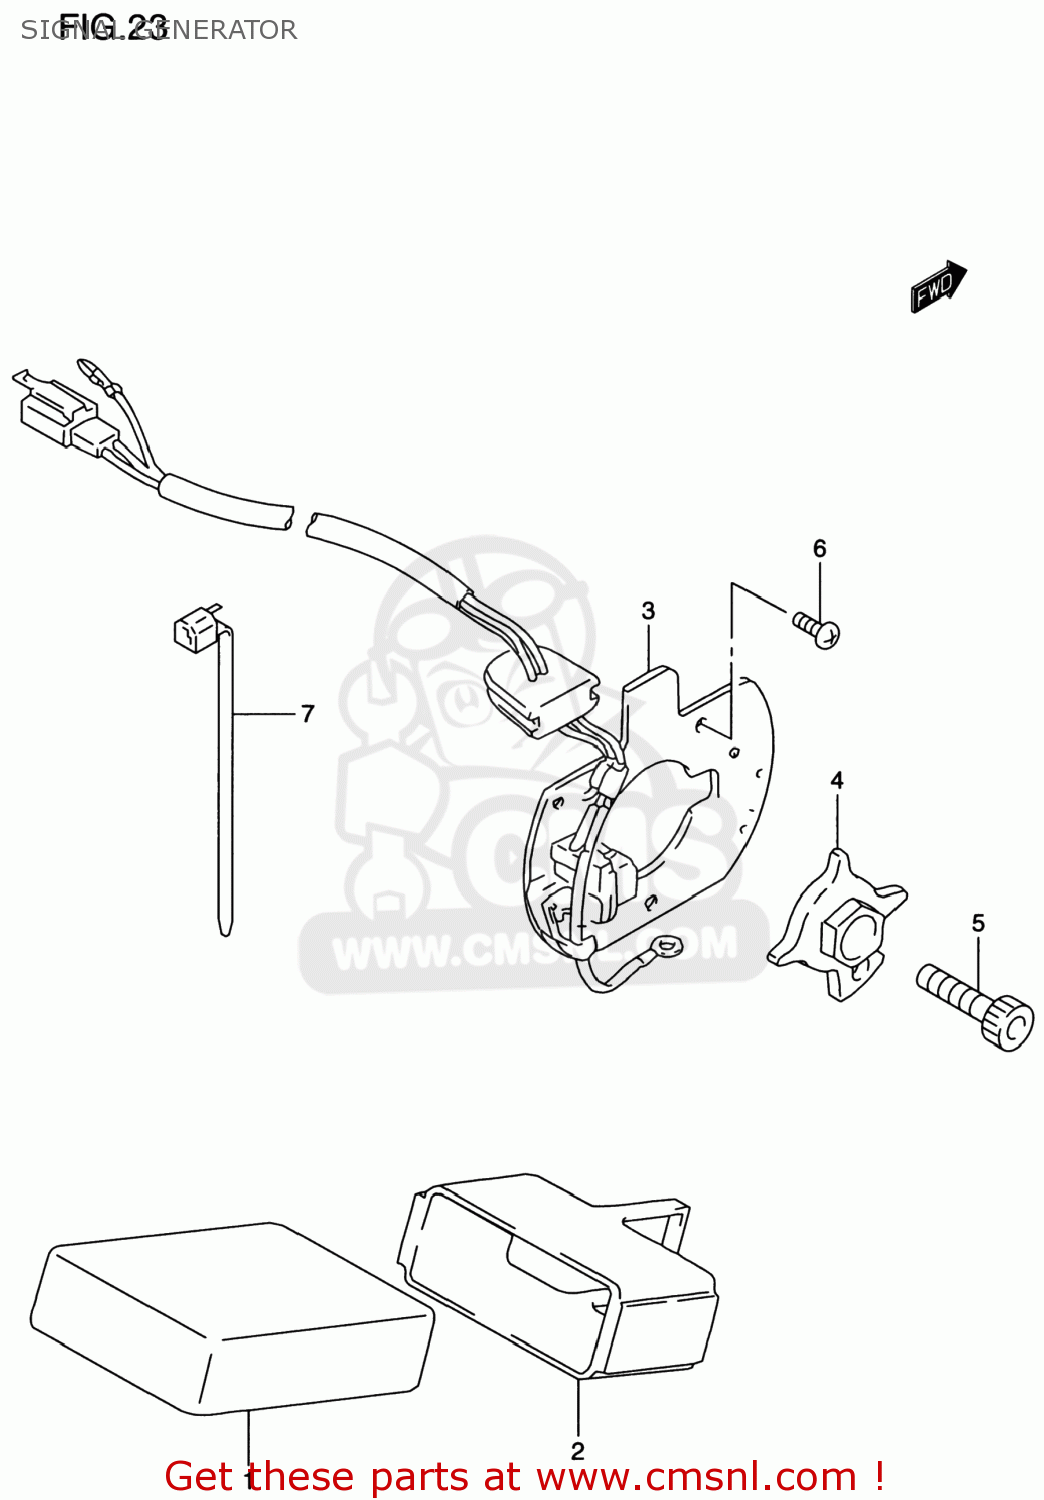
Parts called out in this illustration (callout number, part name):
1	IGNITOR ASSY
2	CUSHION,IGNITOR
3	GENERATOR ASSY,SIGNAL
4	ROTOR,SIGNAL GENERATOR
5	BOLT
6	SCREW
7	CLAMP(L:95)
